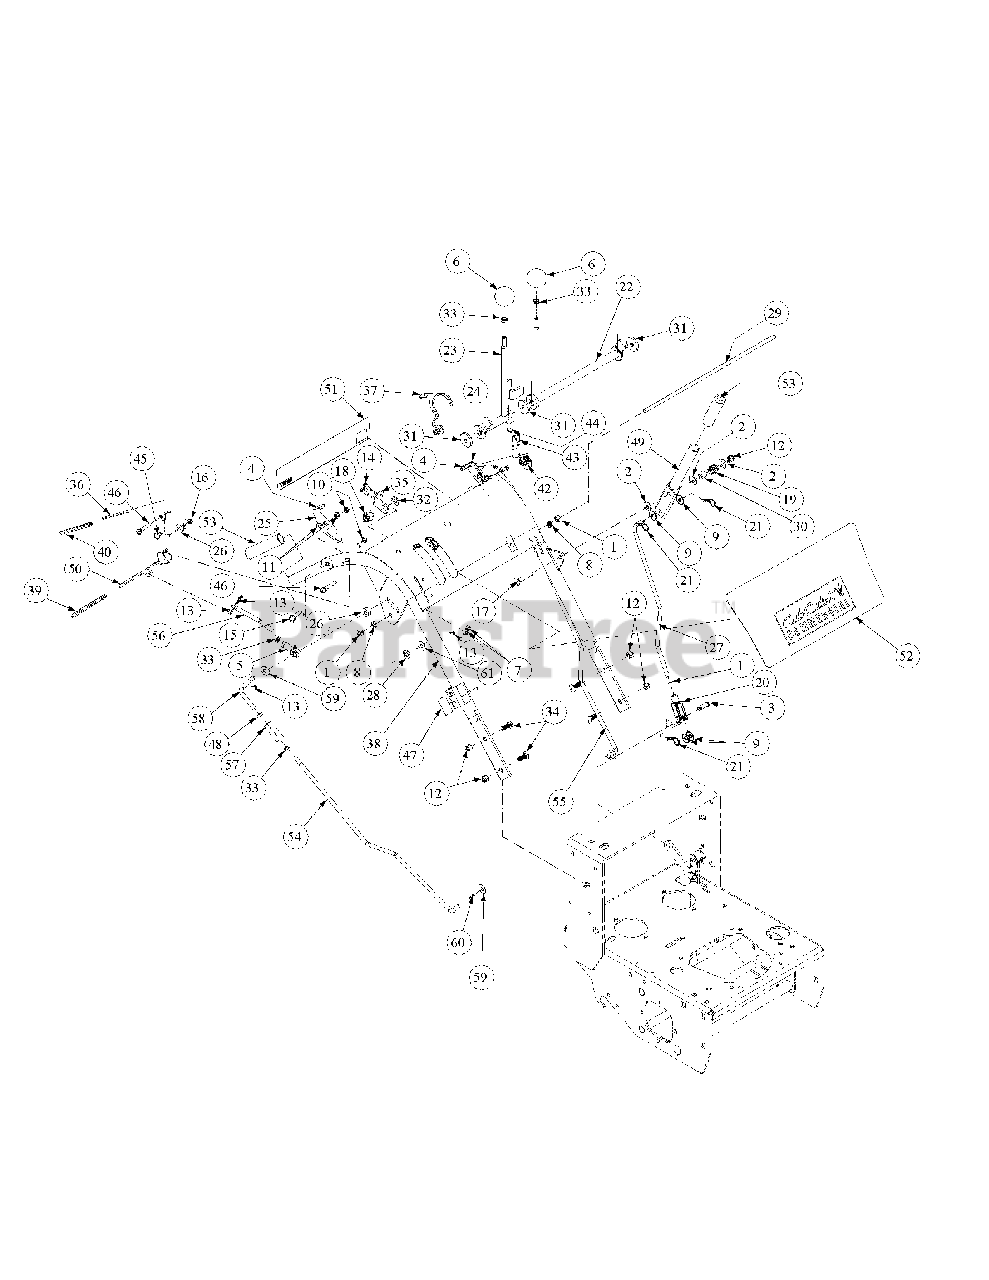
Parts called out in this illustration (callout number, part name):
1	Hex Nut, 3/8 - 16
2	Flat Washer, SS, 3/8
3	Clevis Pin, 3/8 x 1 1/8
4	Grip, 1.25, Black Neutral Lock
5	End Rod, 3/8
6	Knob, 1-3/8 x 1-19/64, 3/8-24
7	Lock Nut, Nylon Insert, 1/4-20
8	Lock Washer, 3/8 Zinc
9	Flat Washer, 3/8, SAE
10	Nut, 5/16-18
11	Flat Washer, SAE 5/16
12	Lock Nut, Nylon Insert, 3/8-16
13	Cotter Pin, 5/32 x 1-1/2 Zinc
14	HHCS, 1/4-20, .75
15	HHCS, Standard, 5/16-18 x 2
16	Lock Nut, Nylon Insert, 1/4 - 28
17	Carriage Bolt, 3/8 -16 x 2
18	Switch Operator's Presence
19	Spring, .850
20	Yoke, 3/8 - 16, Female
21	Hair Pin, 3/8 - 1/2
22	Control Assembly, Speed Hydro, LH
23	Control Assembly, Speed Hydro, RH
24	Latch, RH, Neutral Hydro
25	Latch, LH, Neutral Hydro
26	Hydro, Spacer Control Rod
27	Blade Clutch, Hydro Rod Base
28	Hydro Bush Control Rod
29	Hydro Rod, Speed Control
30	Sleeve Spring, 32/36/48
31	Friction Washer
32	Hex Nut, Dead Man Switch
33	Hex Jam Nut, 3/8-24
34	Carriage Bolt, 3/8 -16 x 2
35	Mounting Switch, Neutral, Safety 2
36	Operator Presence Control Handle, RH
37	Operator Presence Control Handle, LH
38	Hydro, Handle Assembly
39	Control Sleeve, Drive Black
40	Operators Control Sleeve, Yellow
41	Harness Adapter Assembly
42	Snap Mounting Switch
43	Retension Spring
44	Screw, TT, 10-24, .5
45	Shoulder Screw, .38 x .412, 1/4-28
46	HHCS, 5/16-18, 2.00
47	Parking Brake Decal
48	Left Hand Threaded Jam Nut, 3/8-24
49	Clutch Lever Blade
50	Control Lever Assembly
51	Lable Handle
52	Panel Label
53	Black Handle Thin Grip
54	Large Right Control Rod
55	Large Left Control Rod
56	Short Control Rod
57	Turnbuckle
58	Upper Control Rod
59	Flat Washer .406 ID x 1.00 OD
60	Cotter Pin Internal, .072 x 1.12
61	Washer, .469 ID x .875 OD x .105
